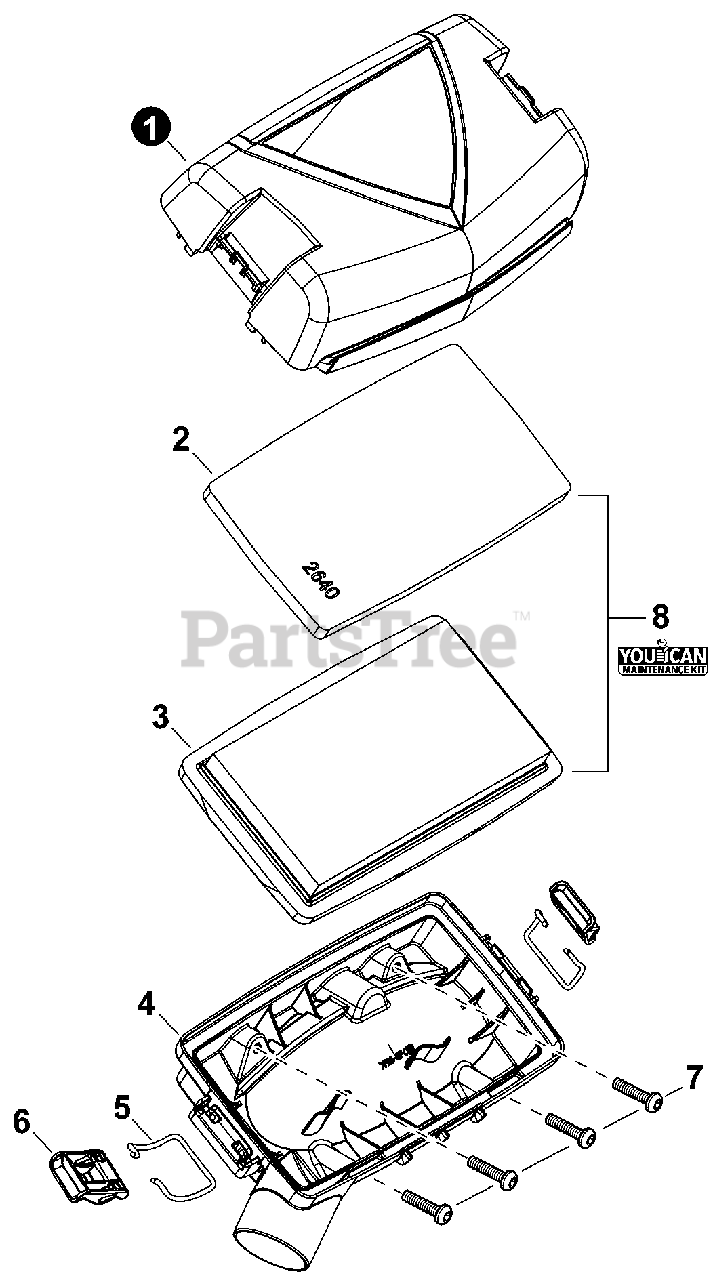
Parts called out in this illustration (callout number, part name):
1	COVER, AIR FILTER
2	PRE-FILTER, FOAM
3	FILTER, AIR
4	CASE, AIR FILTER
5	CLIP, LATCH
6	LATCH, COVER
7	BOLT, TORX 5x20
8	TUNE-UP KIT - YOUCAN?
